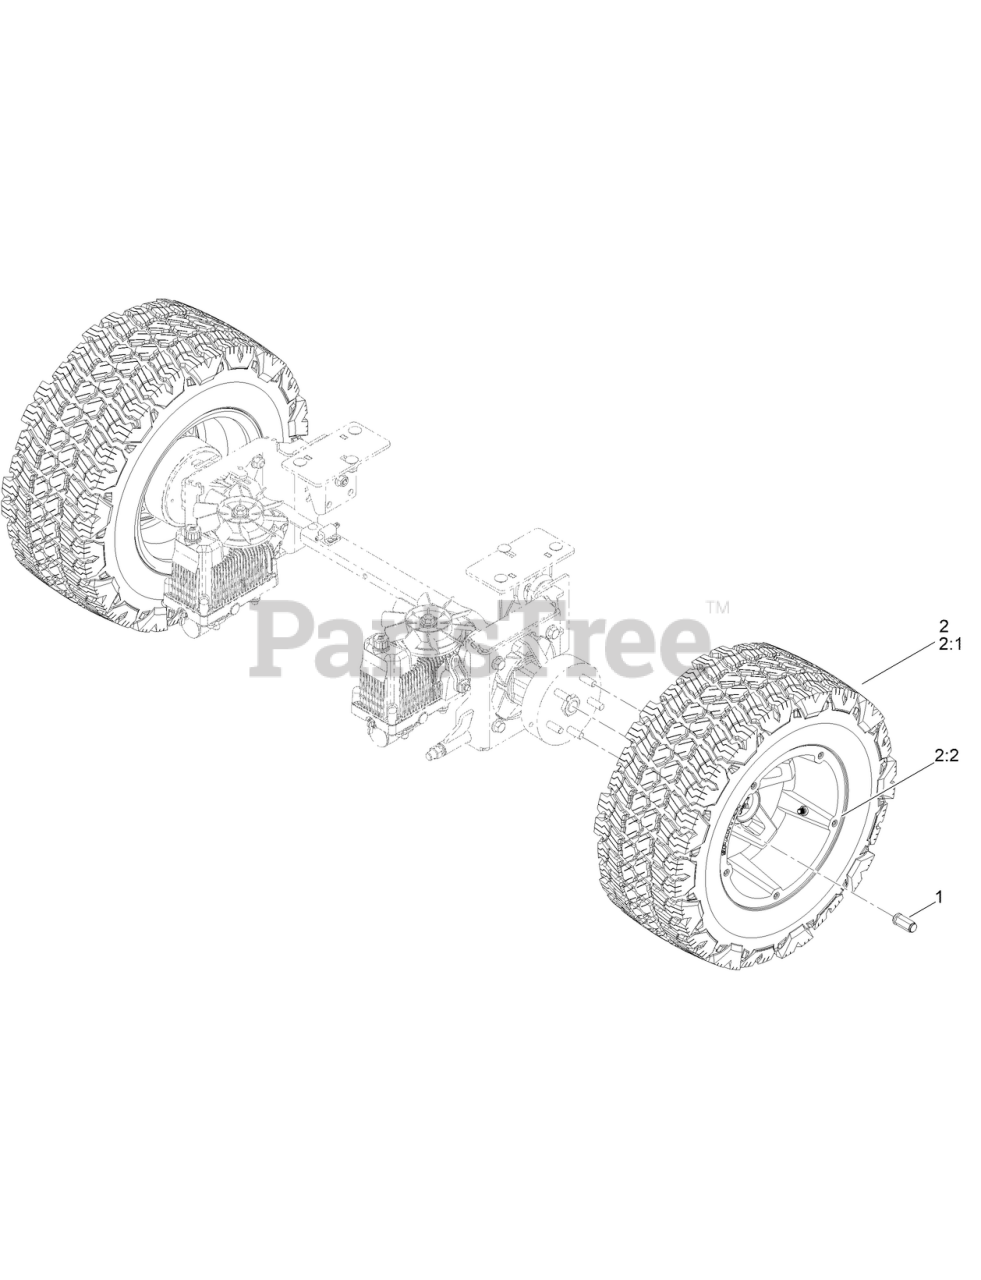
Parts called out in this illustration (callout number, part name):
1	LUG NUTS
2	AL WHL UPGRD (416 WHEEL W/ 24X10.50-R12)
2:1	12 X 8.5 416 STYLE WHEEL ONLY
2:2	MWR 24 X 10.5-12 RADIAL TIRE
